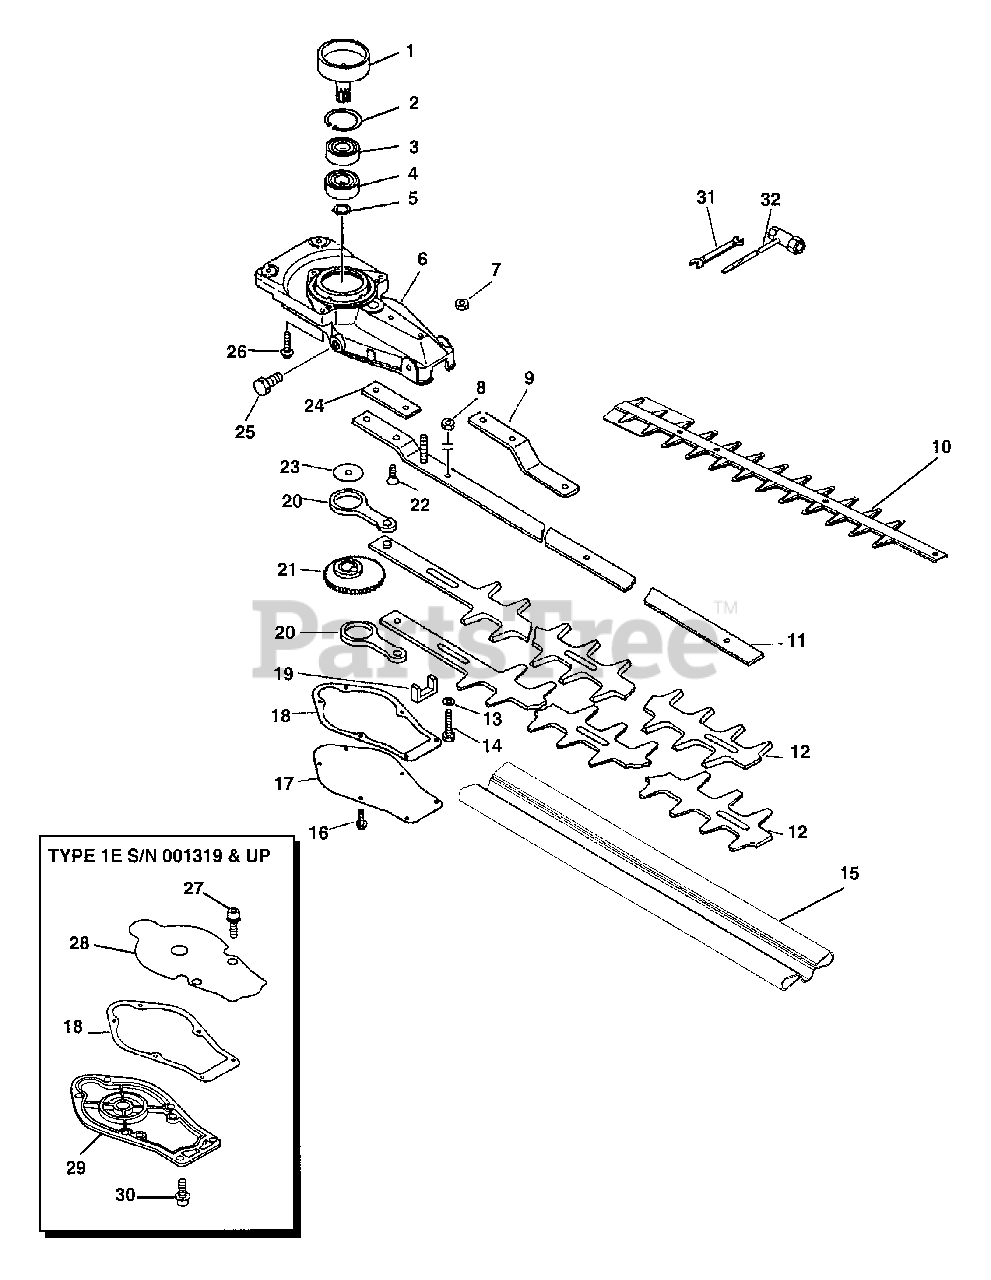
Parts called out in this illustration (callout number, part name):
1	DRUM, CLUTCH
2	RING, SNAP 35
3	BEARING, BALL 6202
4	BEARING, BALL 6202
5	RING, SNAP 14
6	HOUSING, GEAR CASE
6	CASE, GEAR
7	NUT, HEX M6
9	PLATE, ANGLE
10	GUARD, CUTTER BLADE
11	SUPPORT, BLADE
12	BLADE, TRIMMER
13	WASHER 6.5×15.5×0.6
14	BOLT 6×18
14	BOLT 6×20
15	COVER, BLADE
16	BOLT 4×10
17	COVER, GEAR CASE
18	GASKET, GEAR CASE
20	ROD, CONNECTING
22	SCREW 6×25
24	PLATE, EYE
25	BOLT 8×8 SP
26	BOLT 5×25
27	BOLT 5×12
28	PLATE, GEAR CASE
29	COVER, GEAR CASE
30	BOLT 4×12
31	T-WRENCH 13×19×180
32	SPANNER 8×10
